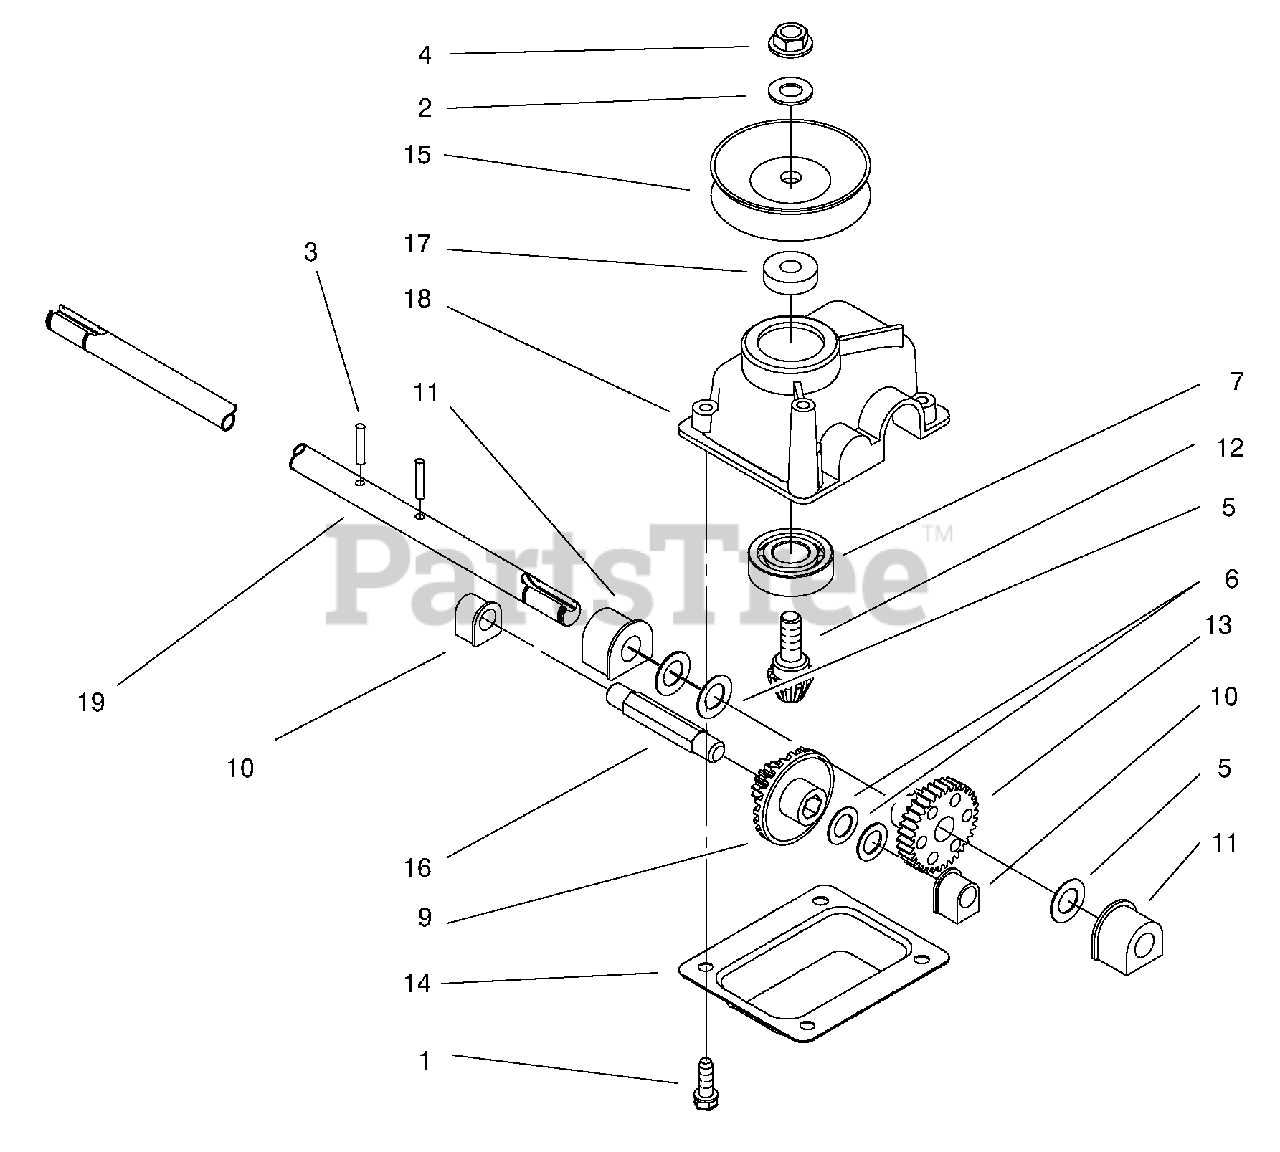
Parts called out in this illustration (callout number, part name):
1	Screw-HH
2	Washer-Flat
3	Pin-Groove
4	Nut-Lock, NI
6	Washer-Thrust
7	Bearing-Ball
9	Gear-Bevel
11	Bushing-Output
12	Gear-Bevel, Pinion
14	Cover-Gear Case
15	Half-Pulley
16	Shaft-Intermediate
18	Gearcase
19	Shaft-Output
